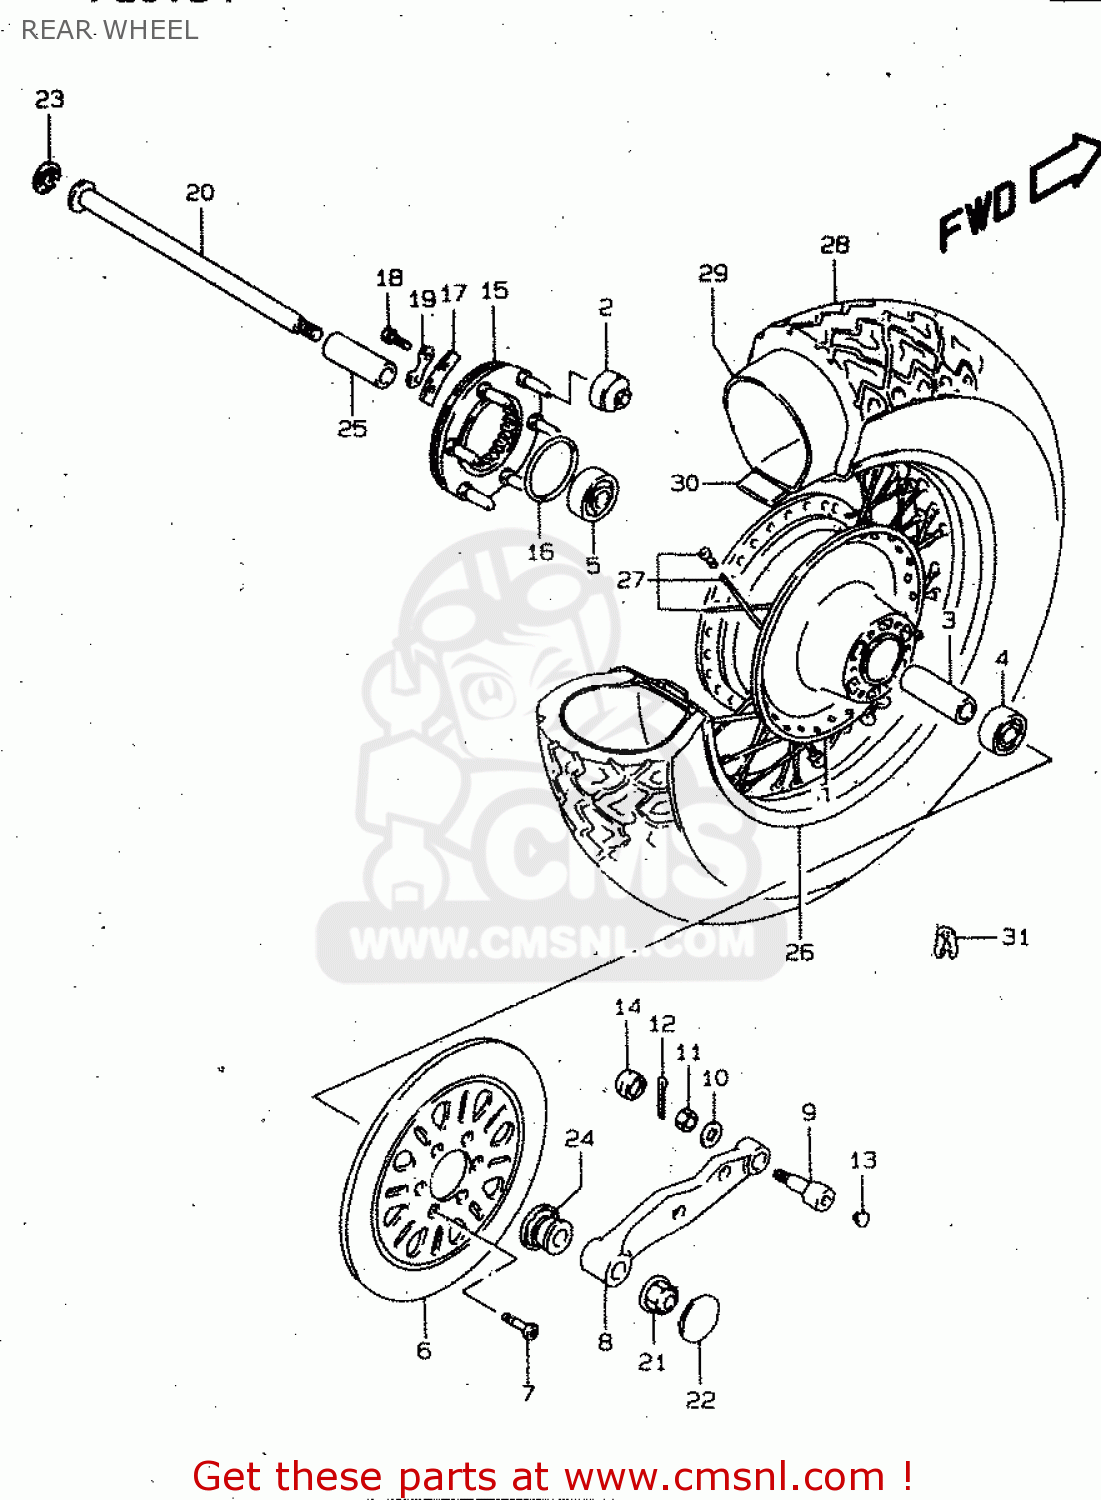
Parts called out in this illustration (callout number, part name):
1	HUB SET,RR
2	BUSH
3	SPACER(17.5X25X113)
4	BEARING
5	BEARING
6	DISC,RR BRAKE
7	BOLT 8X33
8	BRACKET,RR CALIPER
9	PIN,CALIPER BRACKET
10	WASHER(12.5X24X2.6)
11	NUT
12	PIN 20X20
13	CAP(OD:12)
14	CAP
15	JOINT ASSY,RR HUB DRIVEN
16	O RING(D:2.1,ID:65)
17	WASHER,THRUST(T:1.6)
18	BOLT(6X16)
19	WASHER
20	AXLE,RR
21	NUT
22	CAP,RR AXLE,R
23	CAP,RR AXLE,L
24	SPACER,RR AXLE,R
25	SPACER(17.3X25X79.5)
26	RIM,RR WHEEL MT(4.00X1.5)
27	SPOKE SET,RR WHEEL
28	TIRE,RR(170/80 15M/C 77H)
29	TUBE ASSEMBLY,WHEEL,INNER
30	PROTECTOR,WHL INR TUBE
31	BALANCER,WHEEL
